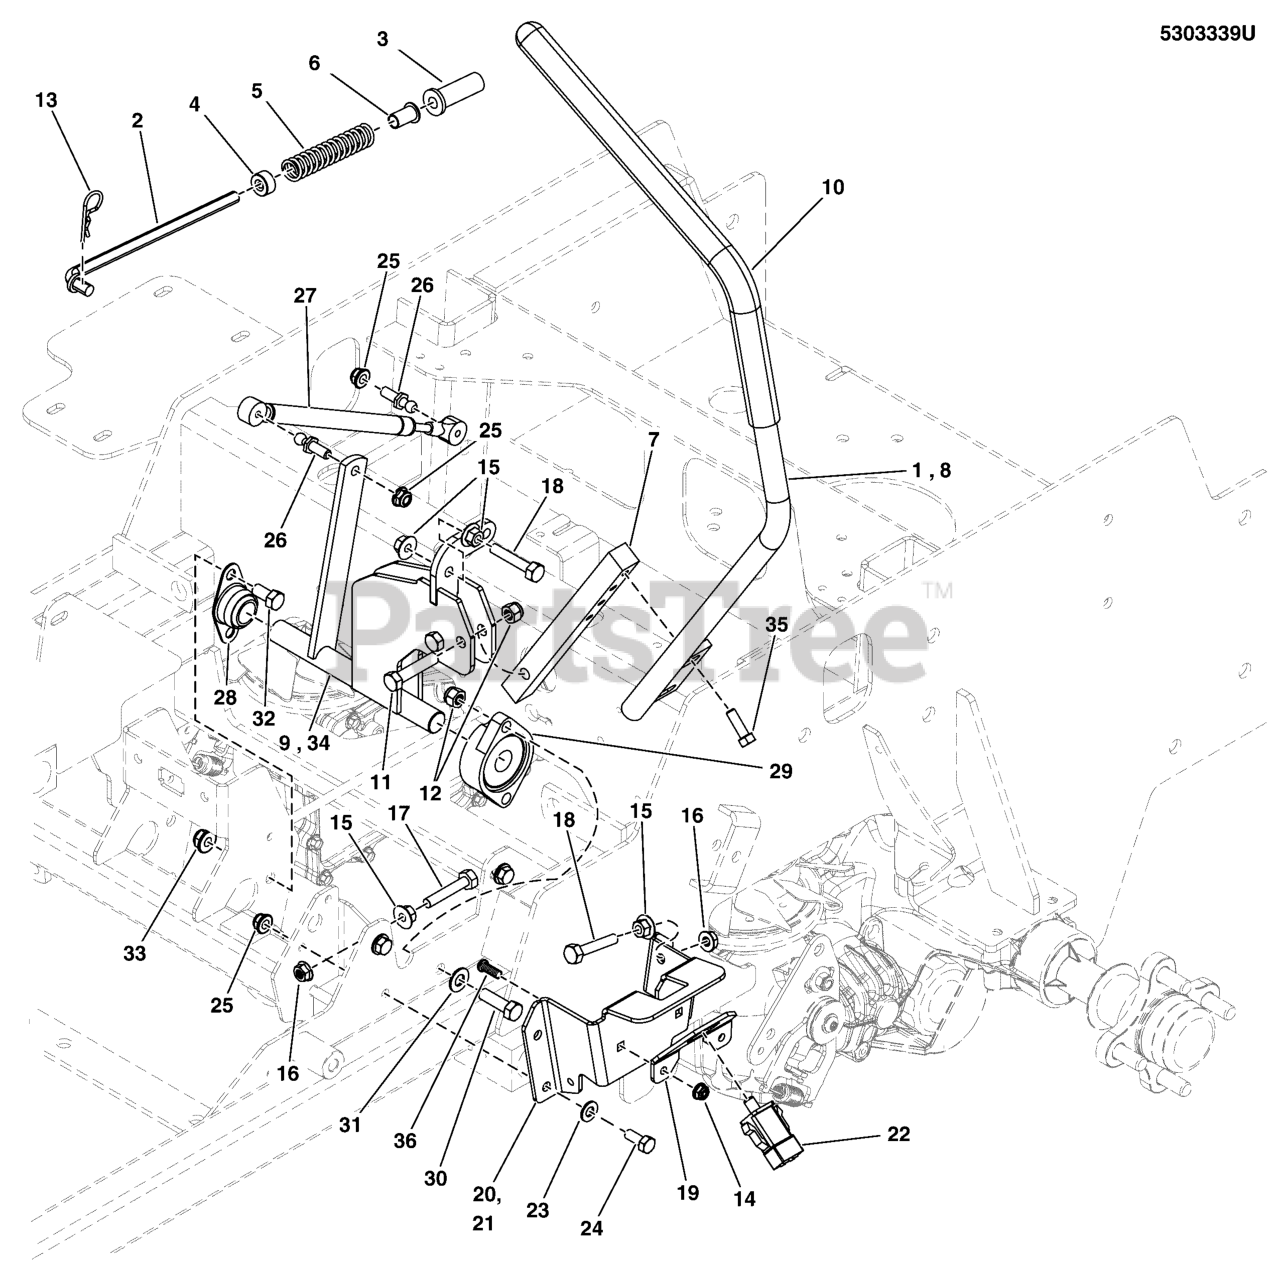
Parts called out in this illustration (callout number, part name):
1	WELD, HANDLE MOTION CONTROL LH - BLK
1	WELD, HANDLE MOTION CNTRL, 19.0, 1.0, LH - BLK
2	ROD, NEUTRAL RETURN, CZ
3	FLANGED BUSHING, 3/8IDX.63ODX.8125FL
4	COLLAR, 3/8" Set
5	SPRING, REVERSE RETURN
6	BUSHING, FLANGE 3/8ID X 7/8 LONG
7	MOUNT, CONTROL ARM - BLK
8	WELD, HANDLE MOTION CONTROL RH - BLK
8	WELD, HANDLE MOTION CNTRL, 19.0, 1.0, RH - BLK
9	WELD, CONTROL SHAFT, RH - BLK
10	GRIP, FOAM, 3/4" ID, 16"" LONG
10	GRIP, FOAM, 1" ID, 16" LONG
11	BOLT, 3/8-16 X 1-3/4" GD5 CZ
12	NUT, 3/8-16 HEX NYLON LOCK
13	3/32 X 1-5/8 HAIR PIN CLIP
14	NUT, 1/4-20 Hex Nylock Flange
15	NUT, 5/16-18 HEX SERRATED FLANGE (LARGE)
16	NUT, 5/16-18 HEX SERRATED FLANGE (SMALL)
17	BOLT- 5/16-18 X 1-1/2 GD5 TFL
18	BOLT, 5/16-18 X 1-3/4 TFL, GD5 YZ
19	BRACKET, SWITCH MOUNT - BLK
20	PLATE, NEUTRAL LOCK, LH - BLACK
21	PLATE, NEUTRAL LOCK, RH - BLACK
22	SEE ELECTRICAL GROUP
23	WASHER, 5/16" SAE
24	BOLT, 5/16-18 X 3/4 GD5
25	NUT, 5/16-18 HEX NYLOCK FLANGE NUT
26	10MM BALL STUD, 5/16-18 X 3/4 THDS
27	DAMPENER, CONTROL,#(P6709/P3610)
28	BEARING, BRONZE FLANGE, 3/4"
29	BEARING, FLANGE
30	BOLT, 3/8-16 X 1-1/4" GD5 CZ
31	WASHER, 3/8 SAE
32	BOLT, 3/8-16 X 3/4" GD5 CZ
33	NUT, 3/8 - 16 HEX NYLOCK FLANGE
34	WELD, CONTROL SHAFT, LH - BLK
35	SCREW, 5/16-18x0.750, GR5, WHIZ-LOCK, ZC
36	BOLT,1/4-20X.75,GR5,RH SH SQ NK,ZNC/CLR
